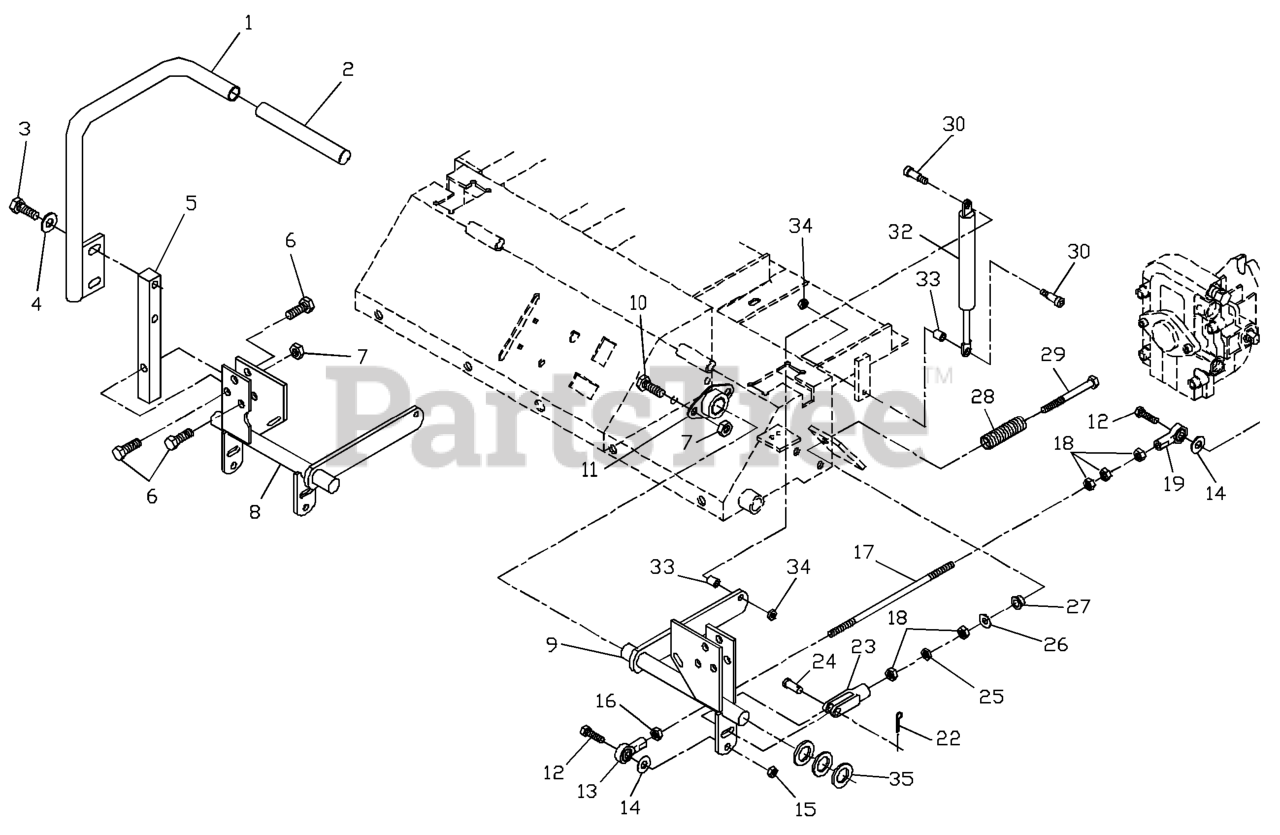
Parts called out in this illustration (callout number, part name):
1	MOTION CONTROL HANDLE, RIGHT
3	HCS 3/8-16X1.GRD.5.ZD
4	WASHER, 3/8 DISC SPRING SPEC
5	CONTROL ARM
6	HCS 3/8-16 X 1 3/4 GR5
7	NUT 3/8C CENTERBLOCK
8	BRACKET, RIGHT
9	BRACKET, LEFT
10	SCREW 3/8C X 3/4 HEX CAP
11	FLANGE BEARING
12	HCS 5/16C X 1 1/4
13	BALL JOINT, LEFT HANDED
14	WASHER 5/16 FLAT
15	NUT 5/16C CENTERLOCK
16	NUT 5/16F LEFTHAND
17	PUMP CONTROL LINK
19	BALL JOINT, RIGHT HANDED
20	PUMP CONTROL ARM
21	SCREW 5/16C X 5/8 SQ HEAD
22	COTTER PIN 3/32 X 1/2
23	YOKE 5/16 ADJ CLEVIS
24	CLEVIS PIN 5/16 X 1
25	NUT JAM 5/16F HEX
26	WASHER 1/4 FLAT
27	BUSHING, NYLON
29	SCREW, NEUTRAL RETURN SHOULDER
30	SCREW, 5/16 X 5/8 SHOULDER
34	NUT 1/4C CENTERLOCK
35	BUSHING, MACH
